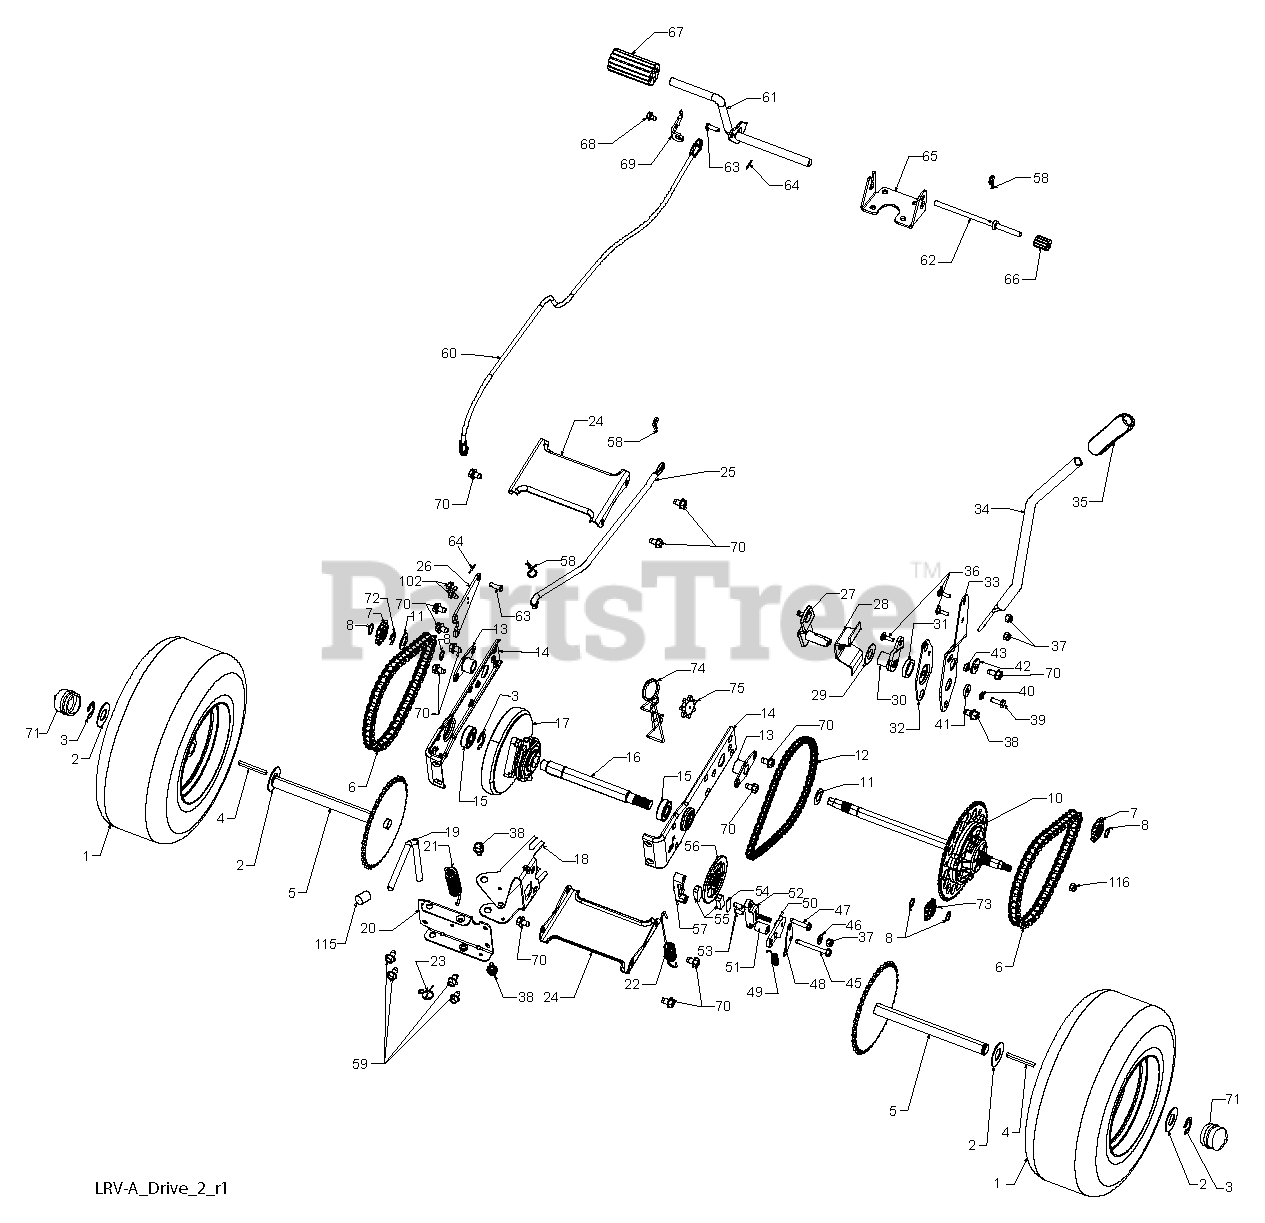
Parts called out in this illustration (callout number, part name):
1	WHEEL.ASM.REAR.LRV.13"MS613
3	E-RING LT
4	SQUARE KEY
5	WELDMENT.AXLE.DRIVEN
6	CHAIN.DRIVE
7	SPROCKET.9.TOOTH.SPLINED
8	SNAP RING
10	DIFFERENTIAL ASM LRV
11	THRUST WASHER
12	CHAIN, PRIMARY DRIVE
13	BUSHING.FLANGE.5/8
14	BRACKET.CARRIER
15	BEARING.BALL
16	SHAFT.INPUT.LRV
17	SUBASM.WHEEL.FRICTION
18	ARM, SHIFT
19	ROD.BYPASS.LRV
20	BRACE CARRIER REAR
21	SPRING, CARRIER
22	SPRING, BRAKE
23	SPRING, BYPASS
24	BRACE CARRIER BOX
25	VALVE.COVER.LCT.414CC.
26	ARM. CLUTCH.LRV
27	WELDMENT SHIFT LEVER
28	RP SUPPORT, SHIFT LEVER
29	WASHER NYLON
30	HUB.SHIFT
31	SPACER.NYLON.
32	MNTG BRKT. SHIFT ARM
33	BRACKET, SHIFTER FLEX
34	TUBE SHIFT ARM
35	GRIP.HANDLE.LIFT.PVC.BLACK
37	LOCKNUT.NYLOC.1/4-20
38	BOLT.SHOULDER.5/16-18X
40	LOCKWASHER
41	WASHER LT
42	WASHER.SRRTD.5/16
43	NUT.71038.31-18.HEX.NYLOCK
45	SCREW.HXWH.THDRL.1/4-20X2.25
46	WASHER
47	SCREW.HXWH.THDRL.1/4-20X1-1/4
48	PLATE.ANTI-ROTATION.BRAKE
49	SPRING, BRAKE RETURN
50	ARM.BRAKE
51	SPACER.RETURN.BRAKE.LRV
52	CALIPER.BRAKE.ASM
53	PIN.DOWEL
54	PLATE, BRAKE PAD
55	PUCK BRAKE
56	ROTOR.BRAKE
57	CAP, BRAKE CALIPER
59	SCREW LT
60	CABLE.BRAKE.
61	SHAFT.ASM.PEDAL.LRV
62	ROD.BRAKE.PARK.LRV
63	PIN.CLEVIS
64	PIN.COTTER.5/64X3/4
65	BRACKET.SUPPORT.BRAKE.LRV
66	COVER.PEDAL.BRAKE.PARKING.LRV
67	COVER.PEDAL.BRAKE.LRV
68	SCREW.1/4-20X3/8
69	BRAKE.MOUNT.CABLE.LRV
70	SCREW
71	CAP.HUB.AXLE.LRVA/B
72	RETAINING RING LT
73	SPROCKET.11 TOOTH.SPLINED
74	TENSION.LRV.CHAIN
75	SPROCKET.IDLER.7TOOTH.LRV
115	CAP.PLUNGER.BLACK
116	NUT LOCK FLG 3/8-16 UNC
